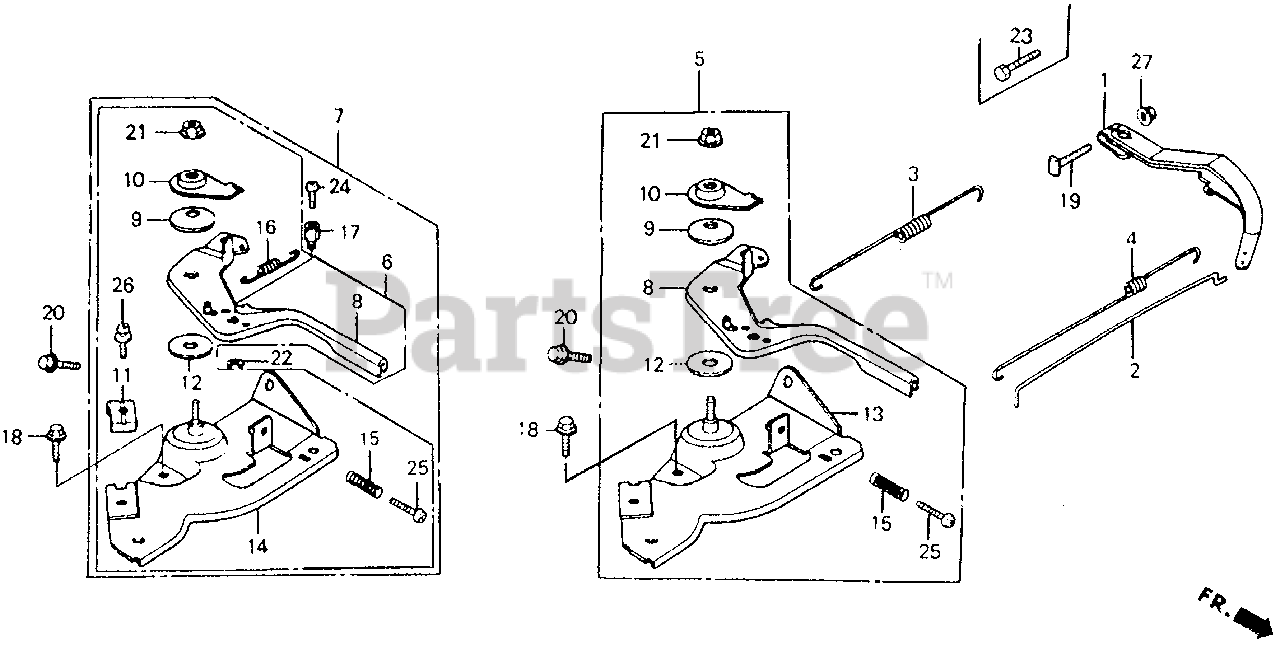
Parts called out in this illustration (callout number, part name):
1	ARM, GOVERNOR
2	ROD, GOVERNOR
3	SPRING, GOVERNOR
4	SPRING, THROTTLE RETURN
7	CONTROL ASSY. (CYCLONE)
8	LEVER, CONTROL
9	SPRING, LEVER
10	WASHER, CONTROL LEVER
11	HOLDER, CABLE
12	SPACER, CONTROL LEVER
14	BASE, CONTROL (CYCLONE)
15	SPRING, CONTROL ADJUSTING
16	SPRING, CABLE RETURN
17	HOLDER, WIRE
18	BOLT, FLANGE (6X12) (CT200)
19	BOLT, GOVERNOR ARM
20	BOLT, FLANGE (6X20) (CT200)
21	NUT, SELF-LOCK (6MM)
22	CIRCLIP (5MM)
24	SCREW, PAN (4X6)
25	SCREW, PAN (5X25)
26	SCREW, PAN (5X16)
26	SCREW-WASHER (5X16)
27	NUT, FLANGE (6MM)
